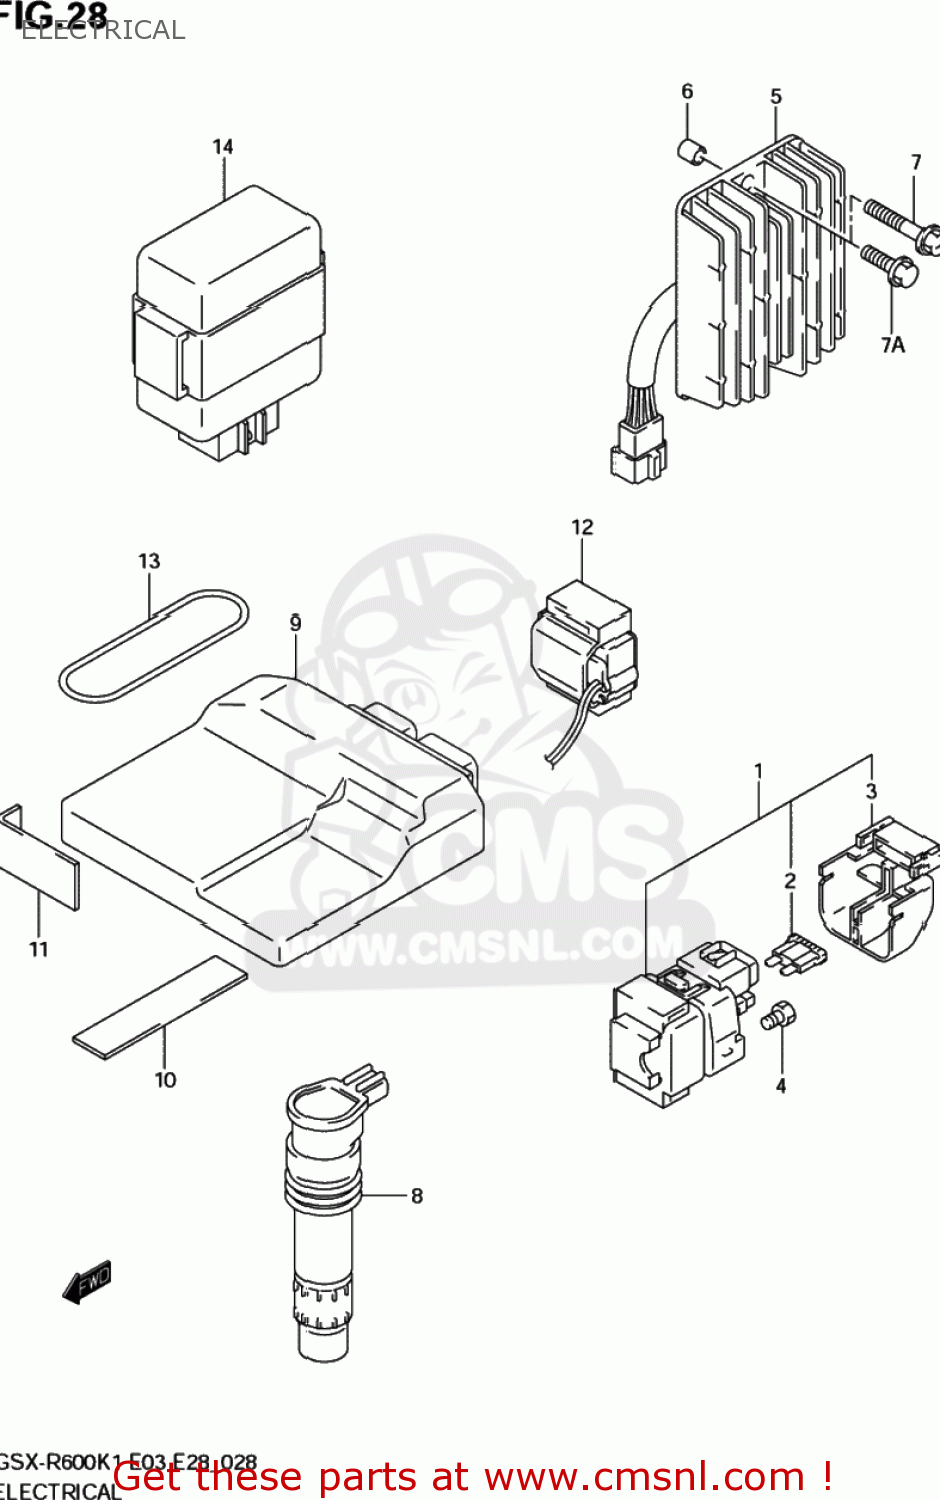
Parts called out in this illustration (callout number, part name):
1	RELAY ASSY,STARTING MOTOR
2	FUSE(30A)
3	COVER,STARTER RELAY
4	SCREW(6X8)
5	RECTIFIER ASY
6	SPACER(6.5X10X7)
7	SCREW
7A	BOLT
8	COIL ASSY,IGNITION
9	CONTROL UNIT,FI
10	PROTECTOR(80X80X2)
11	PROTECTOR(170X95X3.0)
12	SENSOR ASSY,FUEL CUT
13	O RING(D:3.53,ID:69.44)
14	CONTROL UNIT,THROT ACTR
